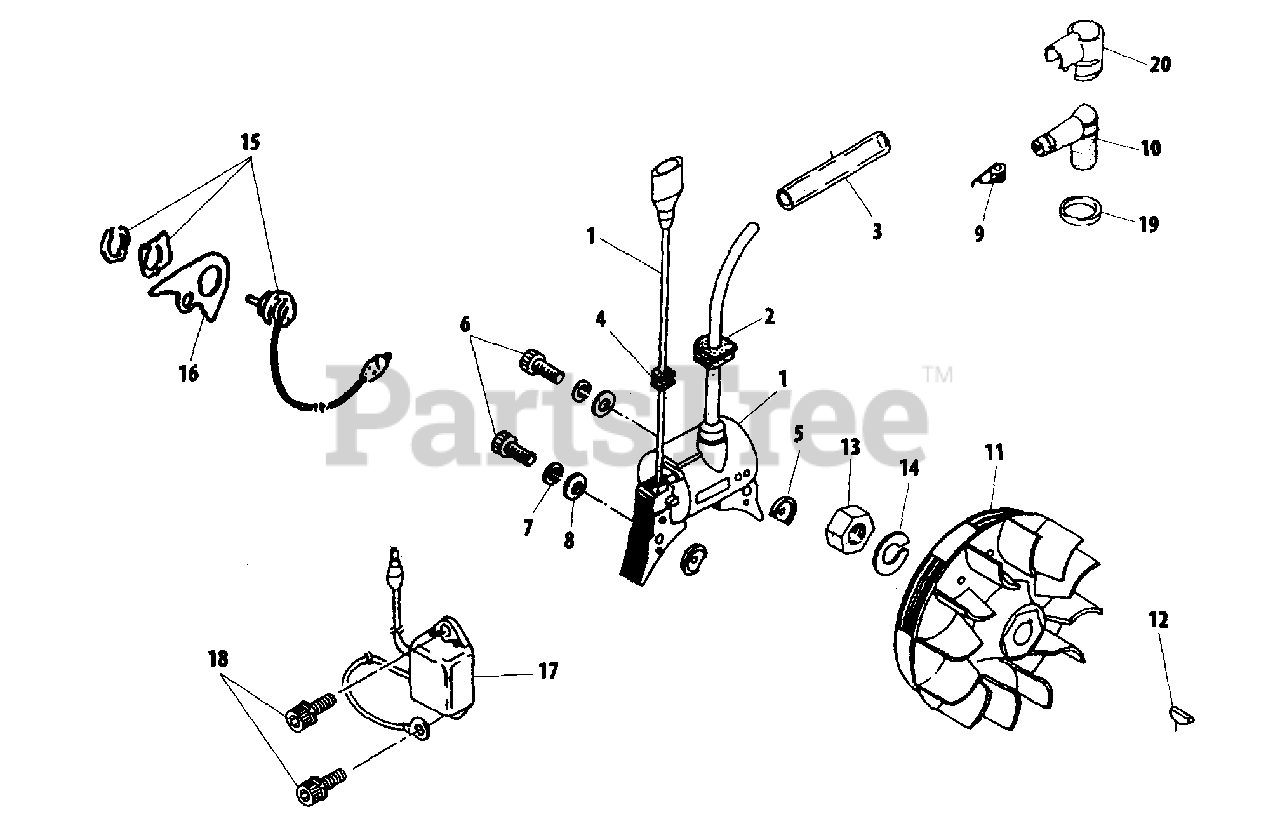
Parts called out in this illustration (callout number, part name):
1	COIL, IGNITION
2	GROMMET
3	TUBE
4	GROMMET
5	INSULATOR
6	SCREW - 4X26
7	LOCKWASHER - 4
8	WASHER
9	TERMINAL, SPARK PLUG CAP
10	CAP, SPARK PLUG
11	FLYWHEEL
12	KEY - 3X10
13	NUT - 10
14	LOCKWASHER - 10
15	SWITCH, IGNITION
16	BRACKET
17	UNIT, ELECTRONIC
18	SCREW - 4X12
19	SEAL, DUST
20	CAP, SPARK PLUG
